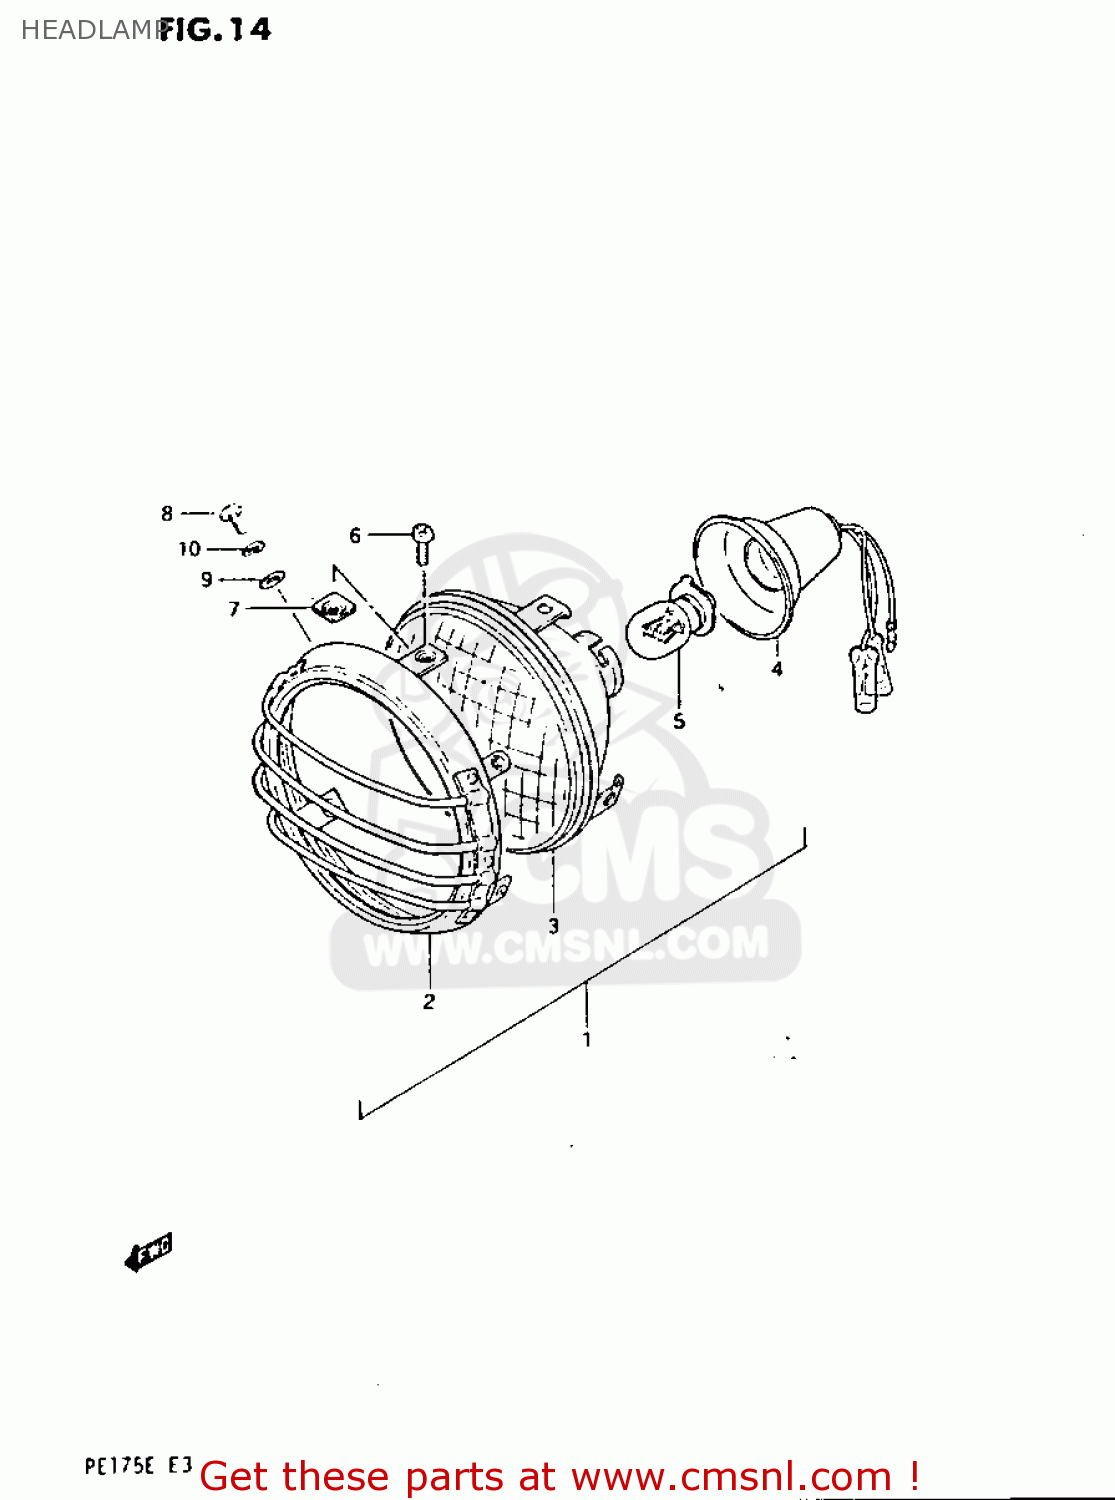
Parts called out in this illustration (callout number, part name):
1	LAMP ASSEMBLY,HEAD
2	RIM,HEADLAMP
3	LAMP UNIT
4	SOCKET,HEADLAMP
5	BULB(6V15/15W/STANLEY,A3598HA)
6	SCREW
7	NUT
8	SCREW
9	WASHER 4MM
10	WASHER,LOCK 4M
